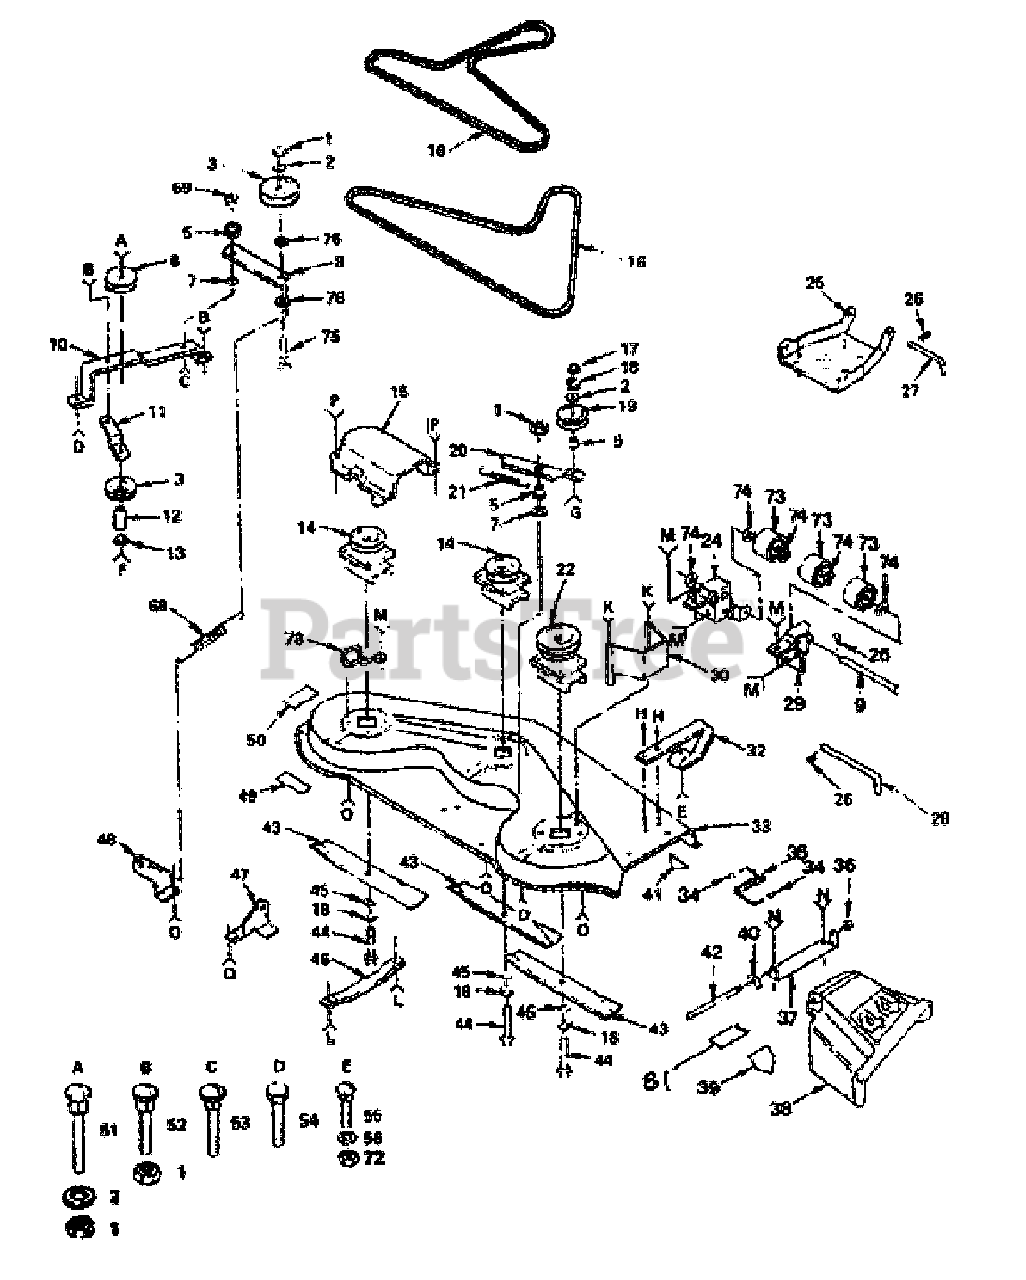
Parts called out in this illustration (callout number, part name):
2	Washer, 13/32 x 1 x 14 Ga.
3	Pulley, Idler
6	Pulley, Idler, Inside
7	Washer, Wear
8	Arm, Idler
9	Pin, Pivot
10	Bar, Support, Idler
11	Brace, Idler, Deck
13	Washer, 13/32 x 13/16 x 16 Ga
14	Mandrel, Secondary
19	Idler, Flat
20	Arm, Idler, Deck
21	Spring, Extension
22	Mandrel, Primary
24	Bracket, Lift, L.H.
25	Link, Parallel
26	Retainer, Spring
27	Pin, Front Hinge
28	Pin, Rear Hinge
29	Bracket, Lift, R.H.
30	Guard, Belt, R.H.
32	Runner, R,H,
33	Housing, Mower
34	Cap, Sleeve
35	Spring
37	Bracket, Deflector
38	Guard, Carriage
39	Decal, Danger
41	Decal, Caution, Deflector
42	Rod, Hinge
43	Blade, Mower, Low, Lift
46	Runner, L.H.
47	Bracket, Suspension, Rear, R.H.
48	Bracket, Suspension, Rear, L.H.
49	Decal, V-Belt, Schematic
50	Instruction, Caution Decal
51	Bolt, Carriage 3/8-16UNC x 1/2
55	Bolt, Carriage 5/16-18 x 3/4
56	Washer, 11/32 x 11/16 x 16 Ga.
61	Washer, 11/32 x 3/4 x 16 Ga
65	Bolt, Carr., 5/16-18 x 5/8 UNC x 3/4
67	Bolt, Carriage 3/8-16 x 3/8
68	Spring, Extension
72	Nut, Lock 5/16-18
73	Roller, Nose
74	Washer, 15/32 x 1 x 10 Ga.
75	Bolt, Carriage, 3/8-16 x 2-1/2
76	Washer, 13/32 x 3/4 x 10 Ga.
77	Washer, 13/32 x 7/8 x 10 Ga.
78	Keeper, L.H. Mandrel
80	Decal, Warning, Swe., Nor., Fin.
81	Decal, Caution, Knife
